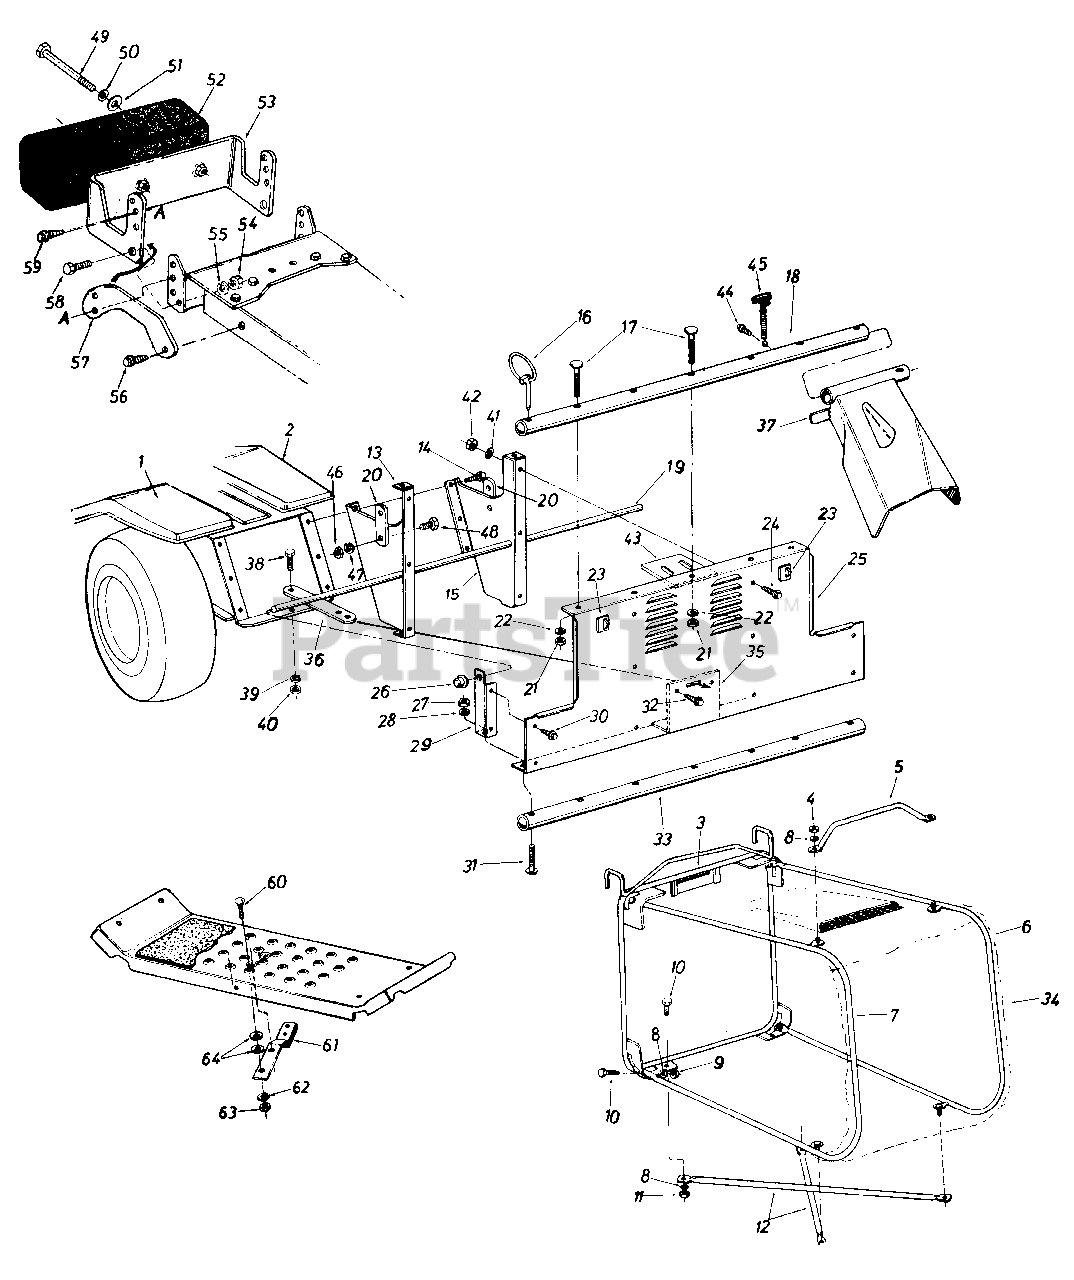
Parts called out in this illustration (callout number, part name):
3	Grass Catcher Frame Ass'y.
4	Hex Cent. L-Nut 1/4-20 Thd.
5	Grass Catcher Handle
9	Hex Cent. L-Nut 1/4-20 Thd.
10	Hex Bolt 1/4-20 x .62" Lg.
11	Hex Cent. L-Nut 1/4-20 Thd.
12	Bottom Cross Brace
13	Grass Catcher Support Brkt.-L.H.
14	Hex Wash. Hd. Self-Tap Scr. 5/16-18 x .75" Lg.
15	Grass Catcher Support Brkt.-R.H.
16	Klick Pin
17	Curved Carr. Bolt 5/16-18 x 1.75" Lg.
18	Grass Catcher Support Tube
19	Tubing .38" I.D. x 39.75" Lg.
20	Fender Support Brkt.
21	Hex Nut 5/16-18 Thd.
22	L-Wash. 5/16" I.D.
23	Safety Switch
24	Hex Wash. Hd. Self-Tap Scr. 1/4-20 x .50" Lg.
25	Grass Catcher Adapter
26	Cap Speed Nut 1/2" Rod
27	Hex Nut 5/16-18 Thd.
28	L-Wash. 5/16" I.D.
29	Chute Extension Support Brkt.-L.H.
30	Hex Wash. Hd. Self-Tap Scr. 1/4-20 x .50" Lg.
31	Curved Carr. Bolt 5/16-18 x 1.75" Lg.
32	Hex Wash. Hd. Self-Tap Scr. 1/4-20 x .50" Lg.
33	Tubing 1.00" I.D. x 40.25"
34	Grass Catcher Bag
35	Hitch Bracket
39	L-Wash. 1/2" I.D.
40	Hex Jam Nut 1/2-13 Thd.
41	Ext. L-Wash. 1/4" I.D.
42	Hex Nut 1/4-20 Thd.
43	Grass Catcher Support Plate
44	Hex AB-Tap Scr. 1/4-20 x .62" Lg.
45	Spring Latch Ass'y.
46	Hex Nut 1/4-20 Thd.
47	L-Wash. 1/4" I.D.
48	Hex Bolt 1/4-20 x .50" Lg.*
49	Hex Bolt 3/8-16 x 4.50" Lg.
50	Bell-Wash. .400" I.D. x .88" O.D.
51	Fl-Wash. .390" I.D. x 1.12" O.D.
52	Front Counterweight
53	Weight Bracket Ass'y.
54	Hex Jam Nut 7/16" Thd.
55	L-Wash. 7/16" I.D.
56	Hex Wash. AB-Tap Scr. 5/16 x 1.0" Lg.
57	Weight Brkt. Tie Strap
58	Hex Bolt 7/16-20 x 1.0" Lg.*
59	Hex Wash. AB-Tap Scr. 5/16 x 1.0" Lg.
60	Carr. Bolt 1/4-20 x .62" Lg.
61	Blade Brake Ass'y.
62	L-Wash. 1/4" I.D.
63	Hex Nut 1/4-20 Thd.*
64	Fl-Wash. .28" I.D. x .75" O.D.
